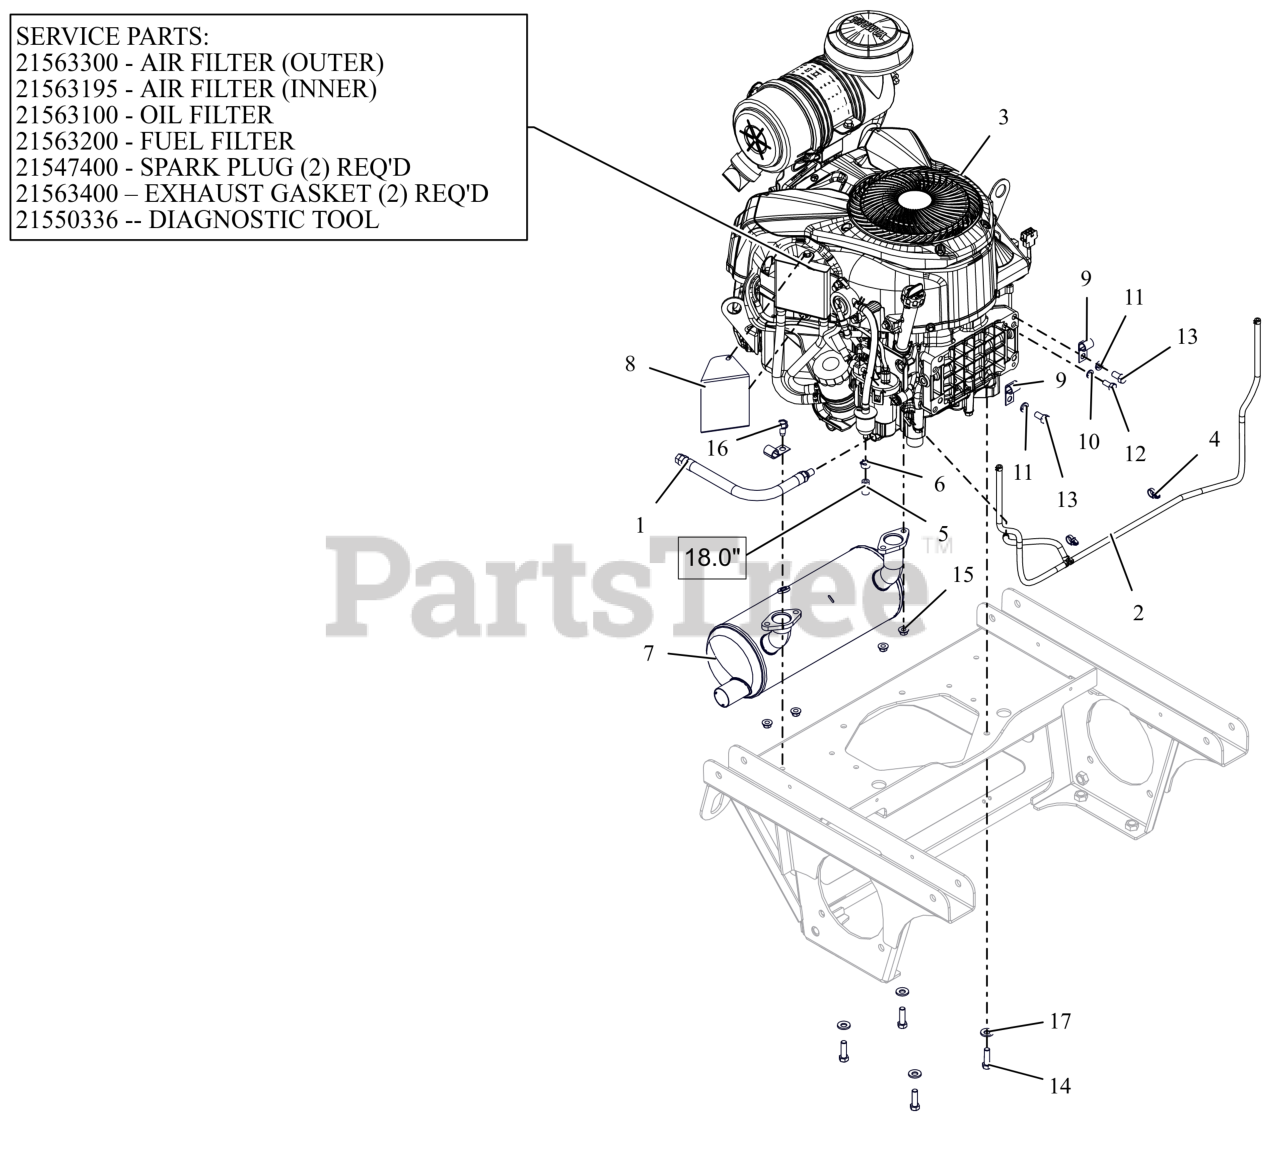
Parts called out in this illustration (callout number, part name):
1	HOSE, OIL DRAIN
2	ASM, YAMAHA VAPOR LINE
3	ENGINE, YAMAHA MX775V-EFI
3	AIR FILTER (OUTER) - YAMAHA
3	AIR FILTER (INNER) - YAMAHA
3	FILTER, OIL - YAMAHA 824
3	FILTER-FUEL YAMAHA 824
3	PLUG, SPARK
3	GASKET, MUFFLER YAMAHA 824
3	DIAGOSTIC TOOL, YAMAHA MXV
4	ROUTING CLIP (1/2" ID)
5	HOSE, .25 LOW-PERM BULK GAS
6	CLAMP, FUEL LINE
7	MUFFLER, YAMAHA
8	DEFLECTOR,YAMAH OIL COOLER AIR
10	WSHR,LK-REG .312X.078 ZCC
11	WSHR,LK-REG .375X.094 ZCC
12	BLT,HEX .31-18X.75 G5 ZCC
13	BLT,HEX .38-16X.75 G5 ZCC
14	BLT, HEX .38-16X1.25 G5 ZCC NT
15	NUT-LK-TOP-FLG M8 ZCC
16	SCR,TAP .375-16X.75 HWH TR ZCC
17	WASHER, 3/8" SPRING DISC
